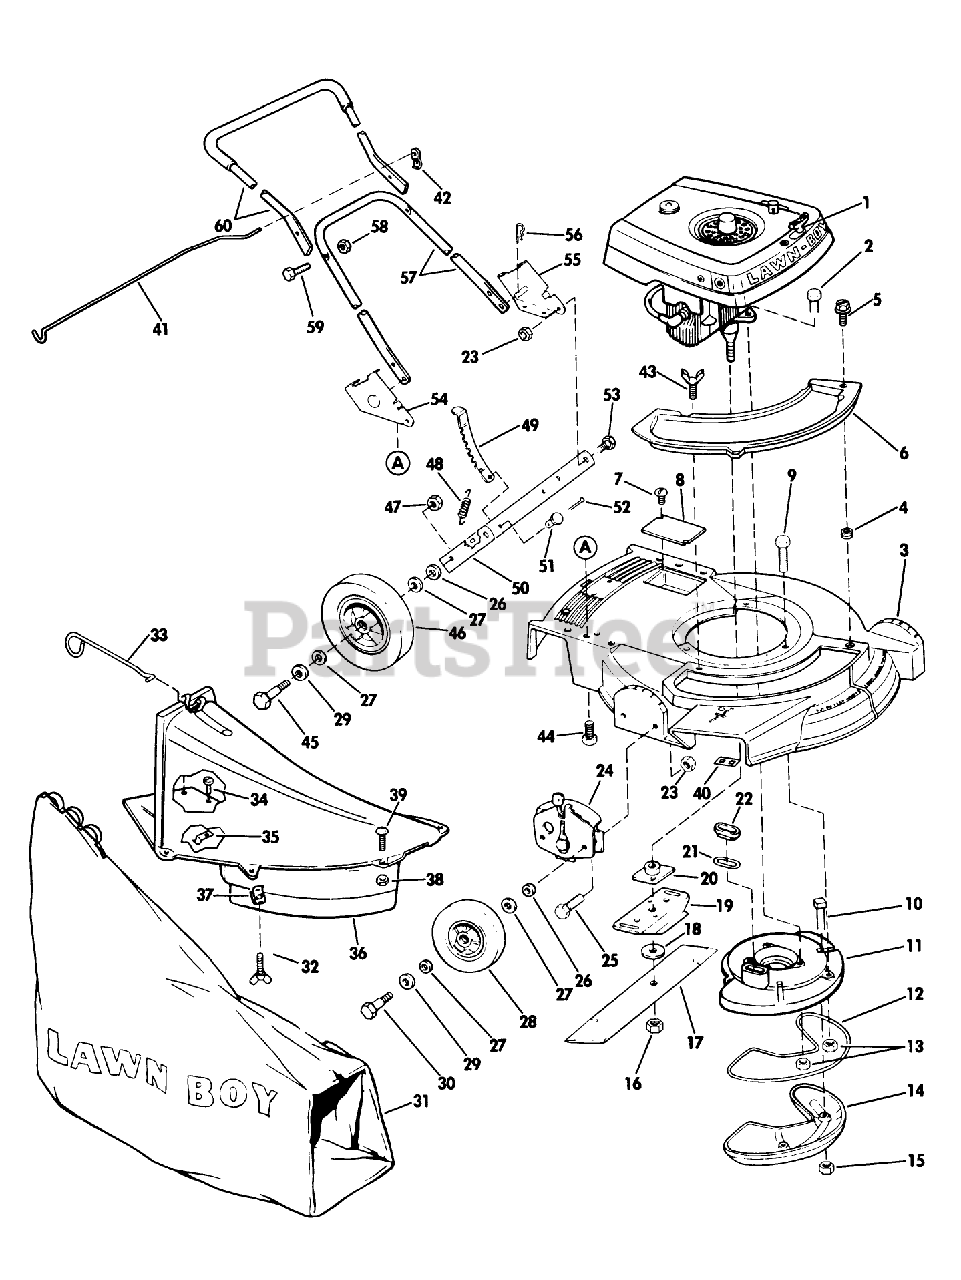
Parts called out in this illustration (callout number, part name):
5	SCREW SEMS TRM HEX HD
15	LOCKNUT E
16	NUT-BLADE
20	PLATE AND COLLAR ASM
21	GASKET S
26	WASHER WROUGHT
30	BOLT WHEEL
31	89802 LB WHOLE GOODS
36	Skirt Assembly
37	SPEED NUT ARDEN
41	ROD & CLIP
47	LOCKNUT
48	SPRING N.A.S
53	BOLT-SHOULDER
56	HAIR PIN
